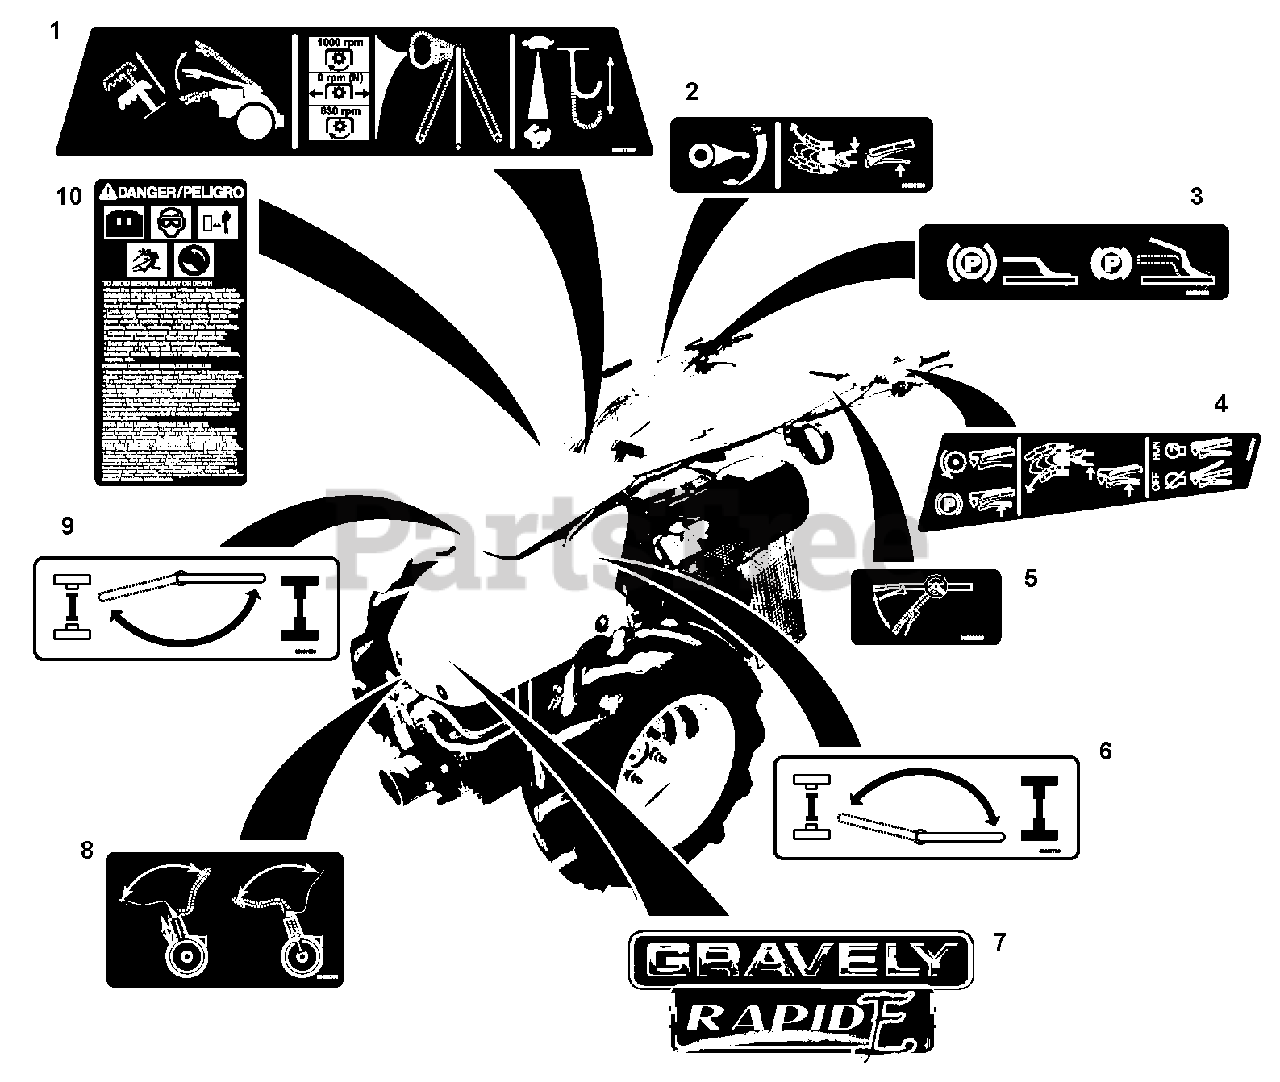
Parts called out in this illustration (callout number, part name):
1	Decal, RAPID E Control Panel
2	Decal, Right Hand Lever Controls
3	Decal, RAPID E Park Brake
4	Decal, Left Hand Lever Controls
5	Decal, RAPID E Handlebar Adjustment
6	Decal, Drive Disengage Right Hand (E)
7	Decal, Gravely Rapid-E
8	Decal, Attachment Lock (E)
9	Decal, Drive Disengage Left Hand E
10	Decal, RAPID E Danger
